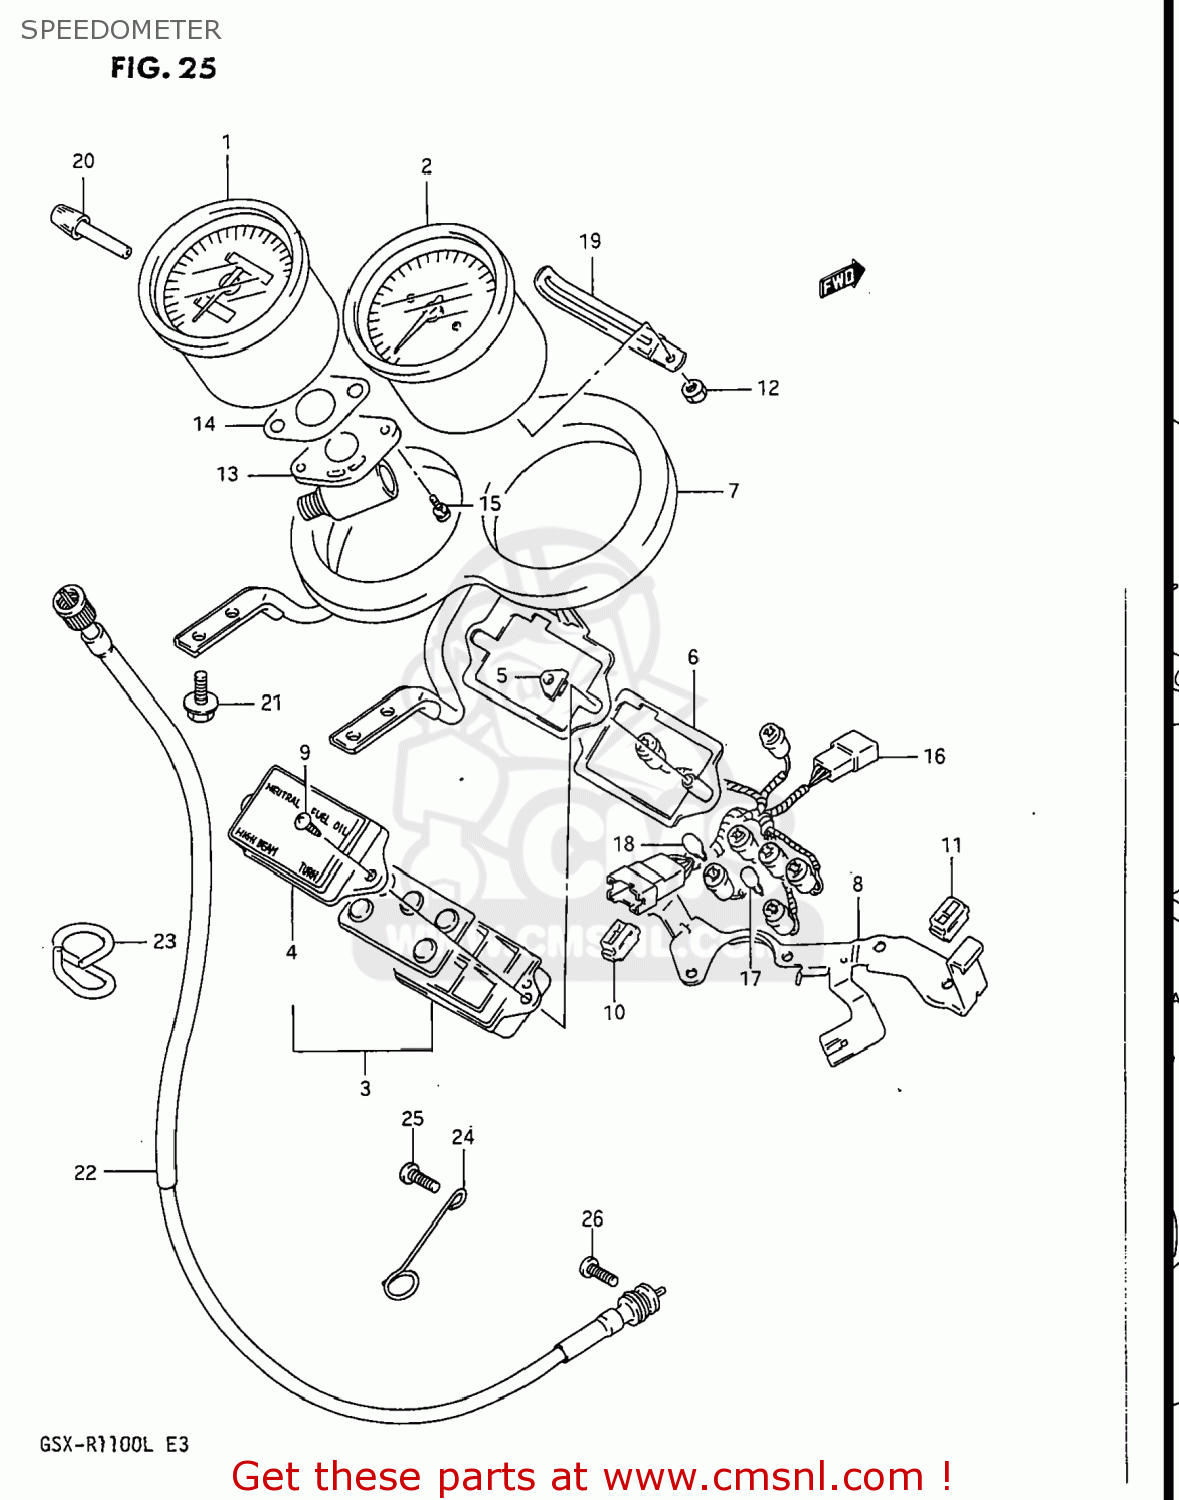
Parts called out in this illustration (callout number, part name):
1	SPEEDOMETER
2	TACHOMETER
3	BOX ASSEMBLY,PILOT LAMP
4	LENS,BOX
5	DAMPER
6	PLATE,SETTING
7	PLATE,SETTING
8	BRACKET
9	SCREW
10	DAMPER,LEFT
11	CUSHION
12	NUT
13	GEAR BOX
14	GASKET,METER GEAR BOX (NAS)
15	SCREW
16	SOCKET,METER
17	BULB(12V3W,T6.5)
18	BULB(12V1.7W,T6.5)
19	CLAMP
20	KNOB,TRIP
21	BOLT 6X12
22	CABLE ASSEMBLY,SPEEDOMETER
23	GUIDE,SPEEDOMETER CABLE
24	GUIDE,SPEEDOMETER CABLE,R
25	SCREW
26	SCREW
